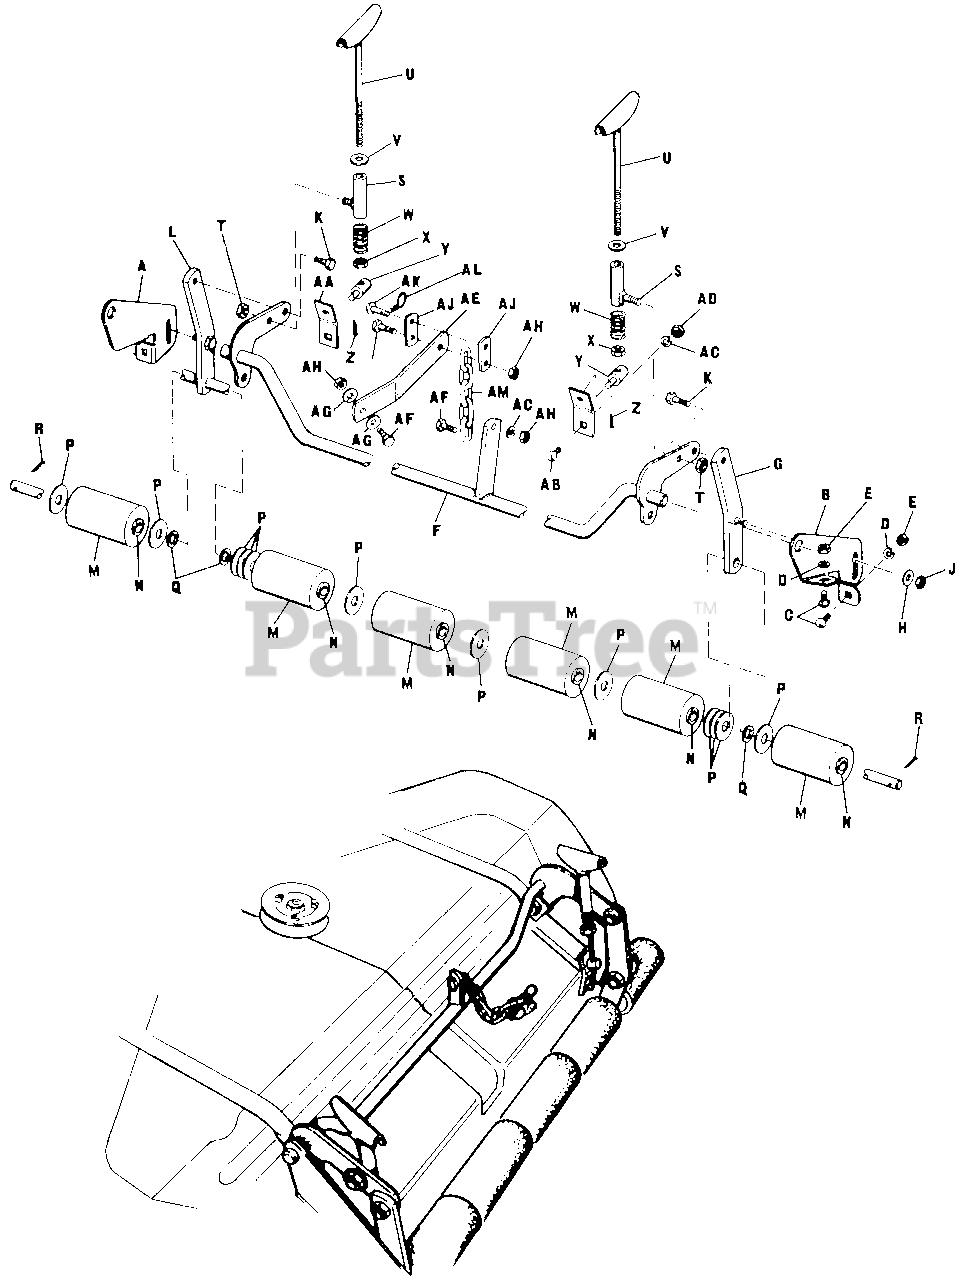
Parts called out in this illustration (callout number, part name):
A	R.H. Roller Bracket
B	L.H. Roller Bracket
C	Carriage Bolt, 3/8"-16 x 3/4"
D	Lock Washer
E	Full Hex. Nut, 3/8"-16
F	Rocker Assembly Arm
G	Roller Bar Assembly L.H.
H	Plain Washer, 3/8"
J	Full Hex. Nut, 3/8"-16
K	Hex. Cap Screw, 3/8"-16 x 1"
L	Roller Shaft Assembly
M	Roller W/Bushing
R	Cotter Pin, 3/16"-1"
S	Socket Crank Assembly
T	Full Hex. Nut, 3/16"-16
U	Adjusting Screw Assembly
V	Plain Washer
W	Adjusting Screw Spring
X	Hex. Jam Nut, 3/8"-16
Z	Cotter Pin, 3/32" x 3/4"
AA	Lift Link
AB	Carriage Bolt, 3/8"-16 x 3/4"
AC	Lock Washer, 3/8"
AD	Full Hex. Nut, 3/8"-16
AE	Mower Lift Lever
AF	Hex. Cap Screw, 3/8"-16 x 1"
AG	Plain Washer, 3/8"
AH	Full Hex. Nut, 3/8"-16
AJ	Mower Lift Link
AL	Spring Clip
